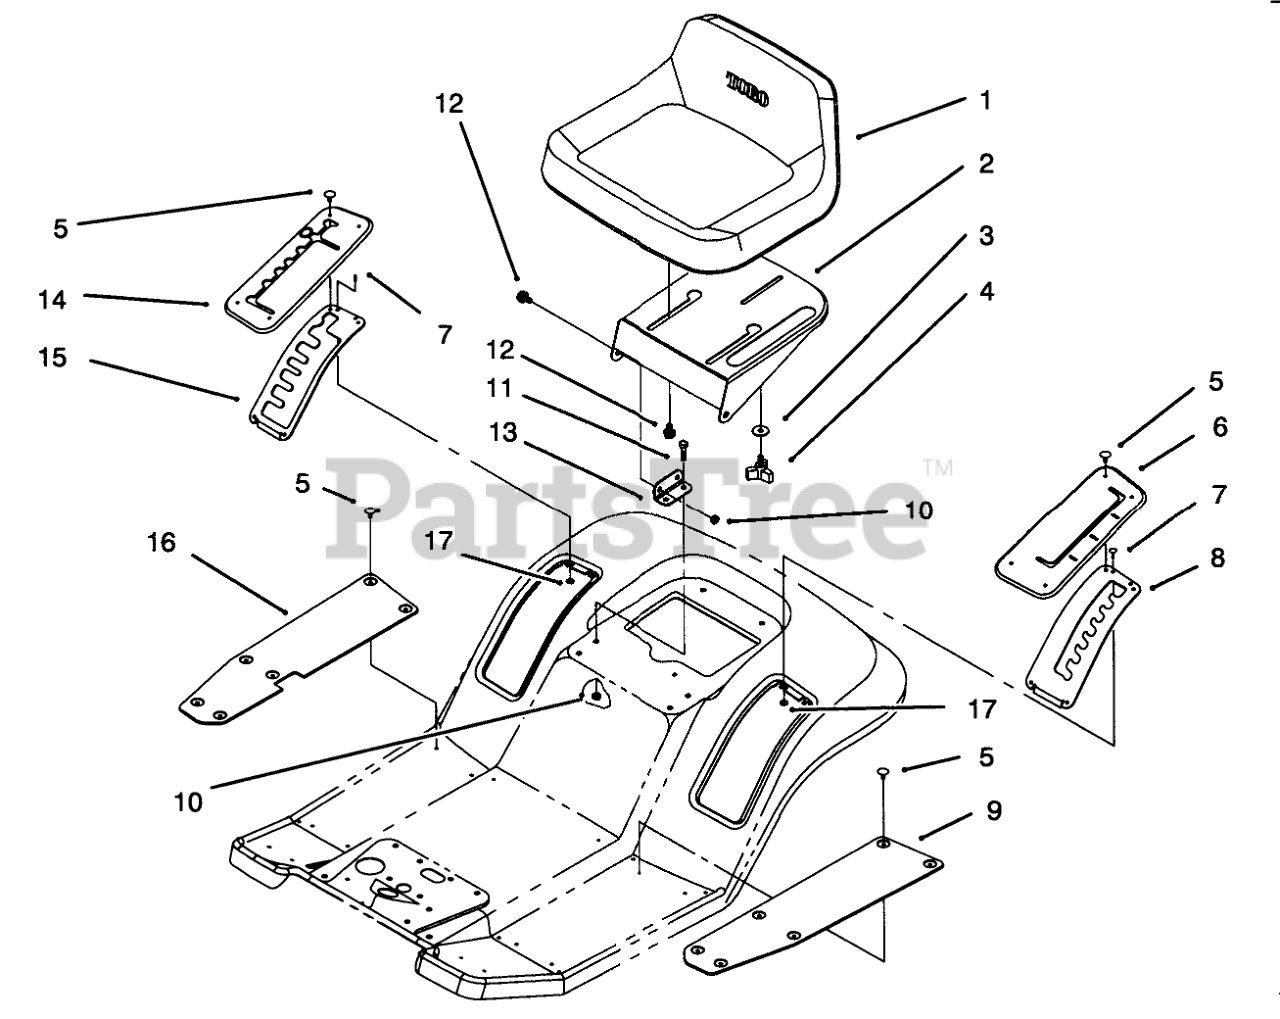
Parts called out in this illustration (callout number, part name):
1	SEAT
2	Support-Seat
3	WASHER-PIVOT
5	FASTENER-PANEL
6	COVER-HOC
7	RIVET-POP
8	Gate-H.O.C.
9	MAT-FOOT, LH
10	NUT-LOCK, NI
11	SCREW-HH
12	BOLT-SHOULDER
13	Bracket-Seat Hinge
14	COVER-GATE, SHIFT
15	Gate-Shift
16	MAT-FOOT, RH
17	WASHER-FLAT
